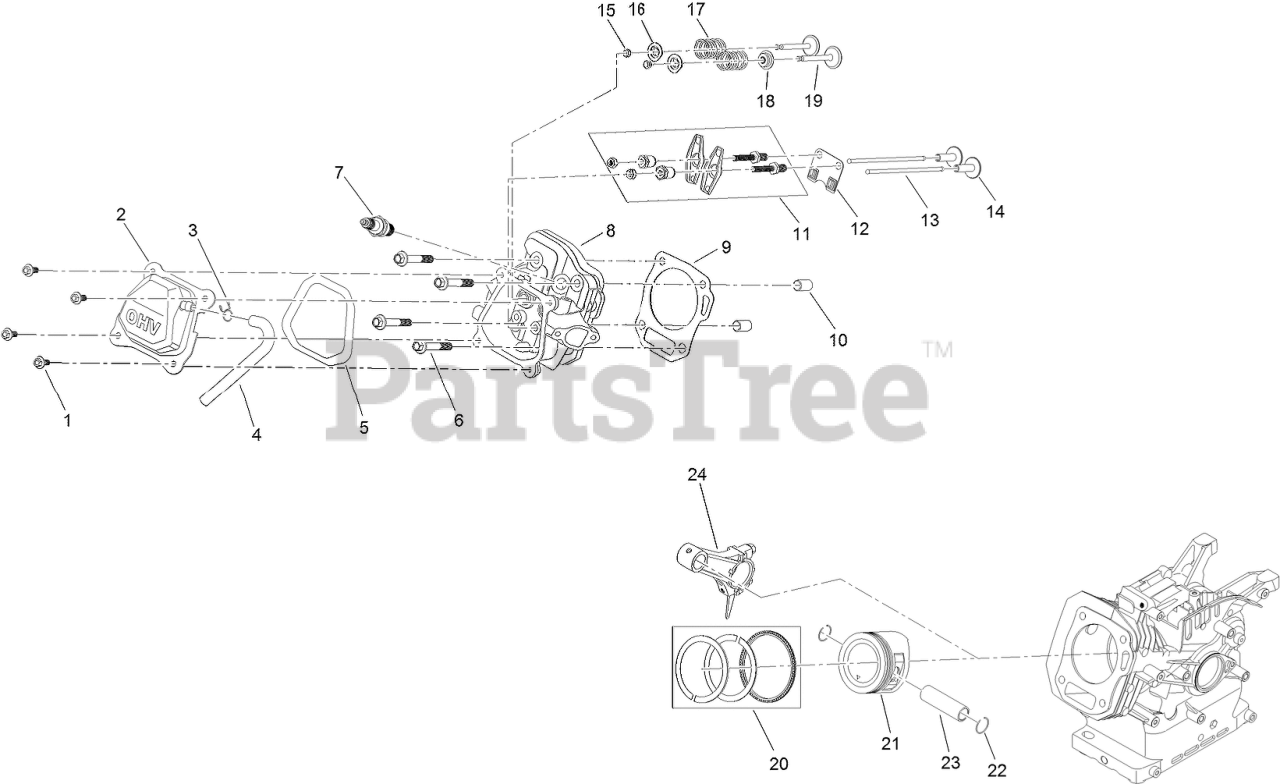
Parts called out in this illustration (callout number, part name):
1	SCREW-HHF
2	COVER-VALVE
3	CLAMP-HOSE
4	TUBE-BREATHER
5	GASKET-COVER, VALVE
6	SCREW-HHF
7	SPARK PLUG
8	HEAD-CYLINDER
9	GASKET-HEAD, CYLINDER
10	PIN-DOWEL
11	ROCKER ARM ASM
12	PLATE-GUIDE, PUSH ROD
13	ROD-PUSH
14	TAPPET-VALVE
15	ROTATOR-VALVE
16	RETAINER-SPRING, VALVE
17	SPRING-VALVE
18	SEAL-STEM, VALVE
19	VALVE SET
20	RING SET, PISTON
21	PISTON
22	CLIP-PIN, PISTON
23	PIN-PISTON
24	CONNECTING ROD ASM
